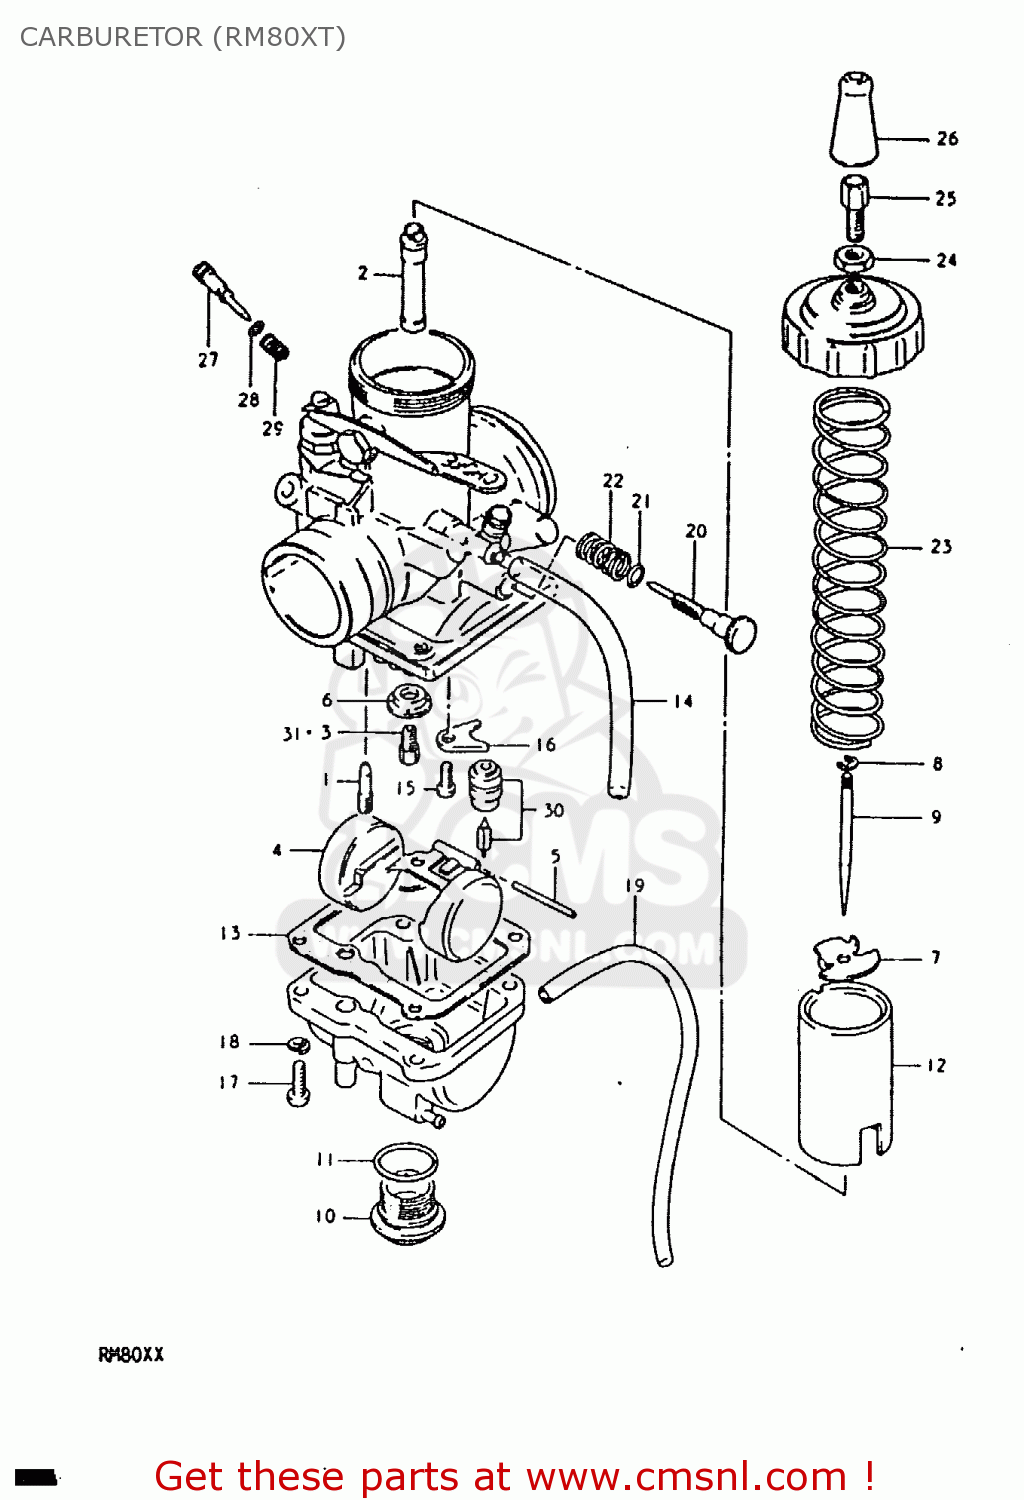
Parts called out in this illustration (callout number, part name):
1	JET,PILOT(50)
2	JET,NEEDLE
3	JET,MAIN(170)
4	FLOAT
5	PIN,FLOAT
6	RING
7	PLATE,THROTTLE VALVE
8	CLIP
9	NEEDLE,JET(5DP39-4)
10	PLUG
11	O RING
12	VALVE,THROTTLE
13	GASKET,FLOAT CAHMBER (NAS)
14	HOSE
15	SCREW
16	PLATE
17	SCREW
18	LOCK WASHER
19	HOSE
20	ADJUSTER
21	O-RING
22	SPRING
23	SPRING, THROTTLE VALVE
24	NUT
25	ADJUSTER,CABLE
26	CAP,CABLE ADJUSTER
27	SCREW,PILOT AIR ADJUSTING
28	O RING
29	SPRING
30	VALVE ASSEMBLY,NEEDLE
